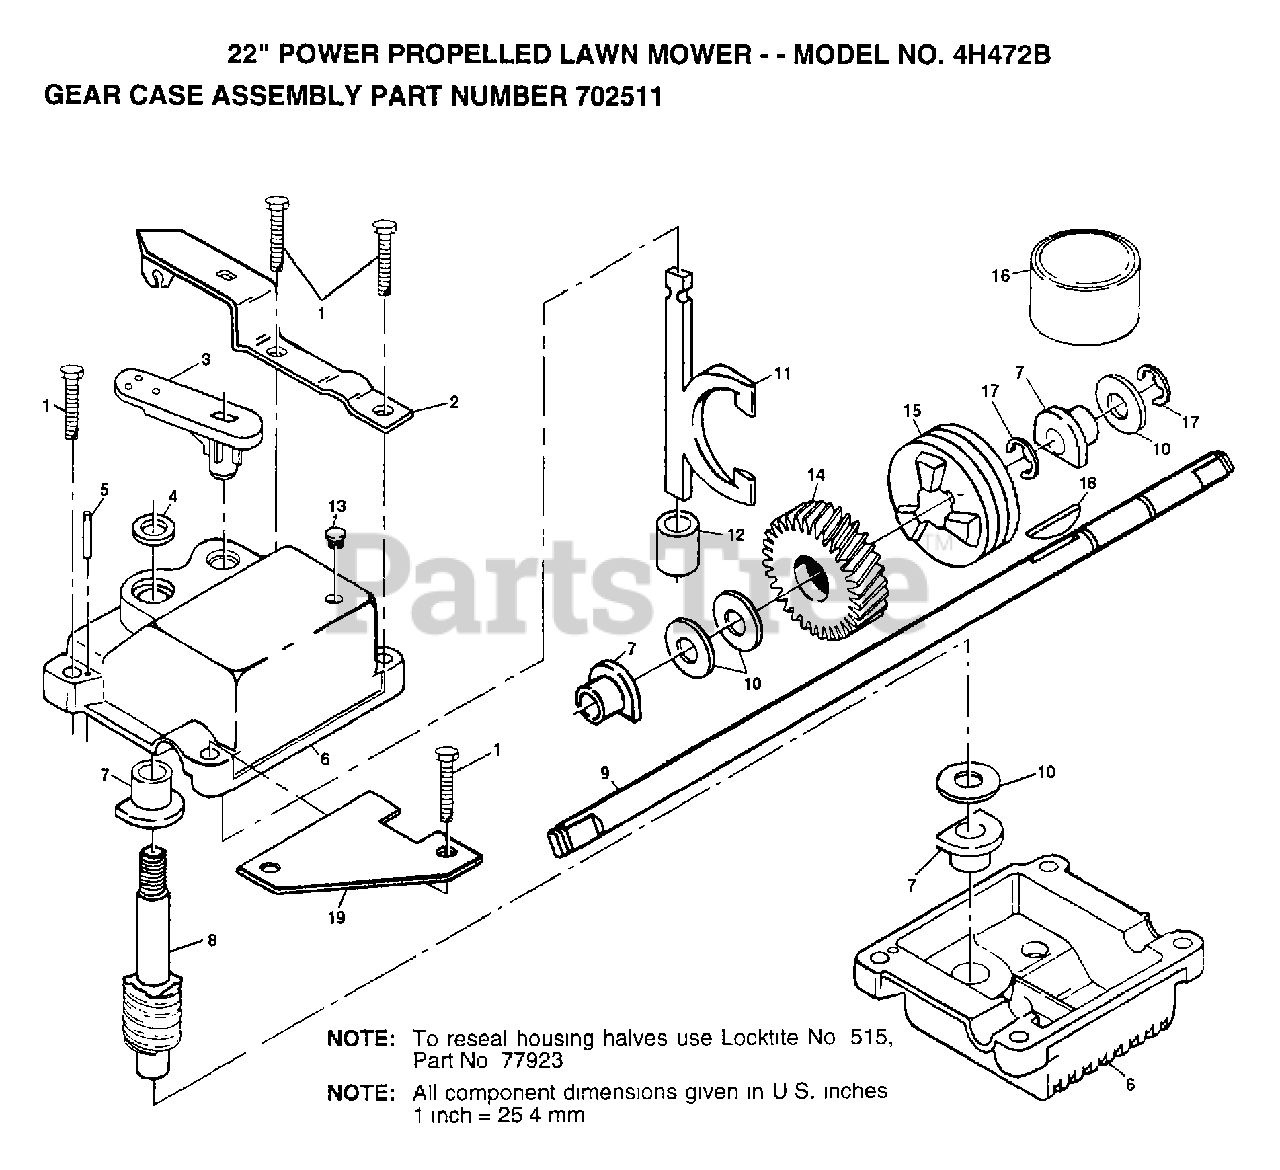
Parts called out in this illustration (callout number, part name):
1	SCREW.1/4-20
2	BRACKET.GEARCASE
3	SHIFTER
4	SEAL
5	PIN GROOVED 1/8X5
6	KIT GEARCASE HALV
7	BEARING
8	SHAFT.WORM
9	SHAFT.DRIVE
10	THRUST WASHER
11	CLUTCH YOKE
12	BUSHING.GEAR BOX
13	PLUG PM
14	GEAR.HELICAL
15	CLUTCH JAW
17	RING T
18	HI PRO KEY
